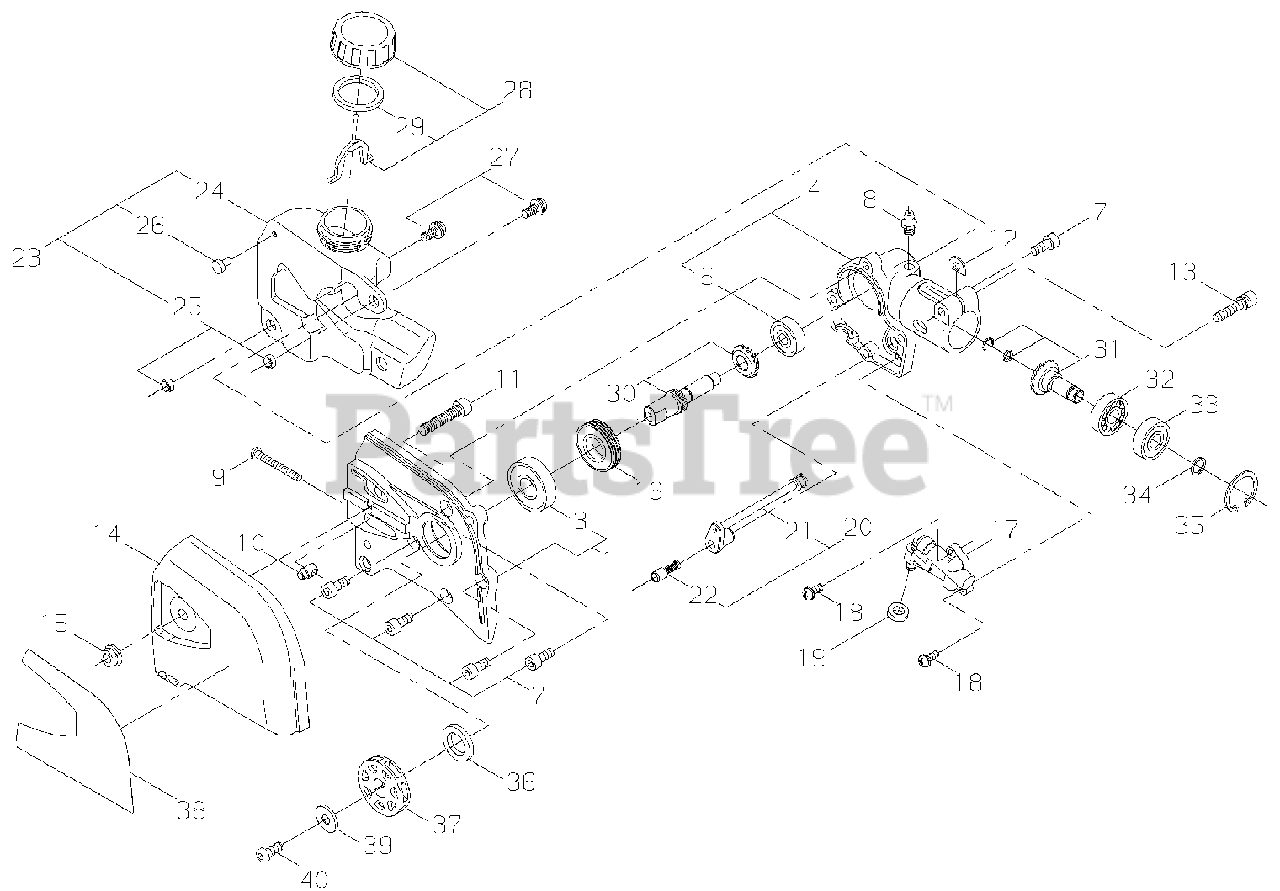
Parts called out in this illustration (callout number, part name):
3	BEARING, BALL - 6001DDU
4	GEARCASE ASSY - RIGHT
6	BEARING, BALL - 627ZZ
7	SCREW - 5X12
8	GREASE NIPPLE
9	SCREW - 4X35
10	TENSIONER, CHAIN
11	SCREW - 6X30
12	SHIM
13	SCREW - 5X25
14	BAR HOLDER
15	NUT - 6 -- FLANGE
16	GEAR - WORM
17	AUTO-OILER ASSY
18	SCREW - 4X10
19	GASKET, PUMP
20	OIL PIPE ASSY
21	PIPE - OIL
22	FILTER
23	OIL TANK ASSY
24	TANK, OIL
26	VALVE, OIL
27	SCREW - 5X12
28	OIL CAP ASSY
29	GASKET, CAP
30	GEARSHAFT
31	GEAR - BEVEL
32	BEARING, BALL - 609
33	BEARING, BALL - 609ZZ
34	RING, RETAINING
35	RING, RETAINING - 24
36	COLLAR
37	SPROCKET
38	LABEL - CAUTION
39	WASHER
40	SCREW - 6X14
